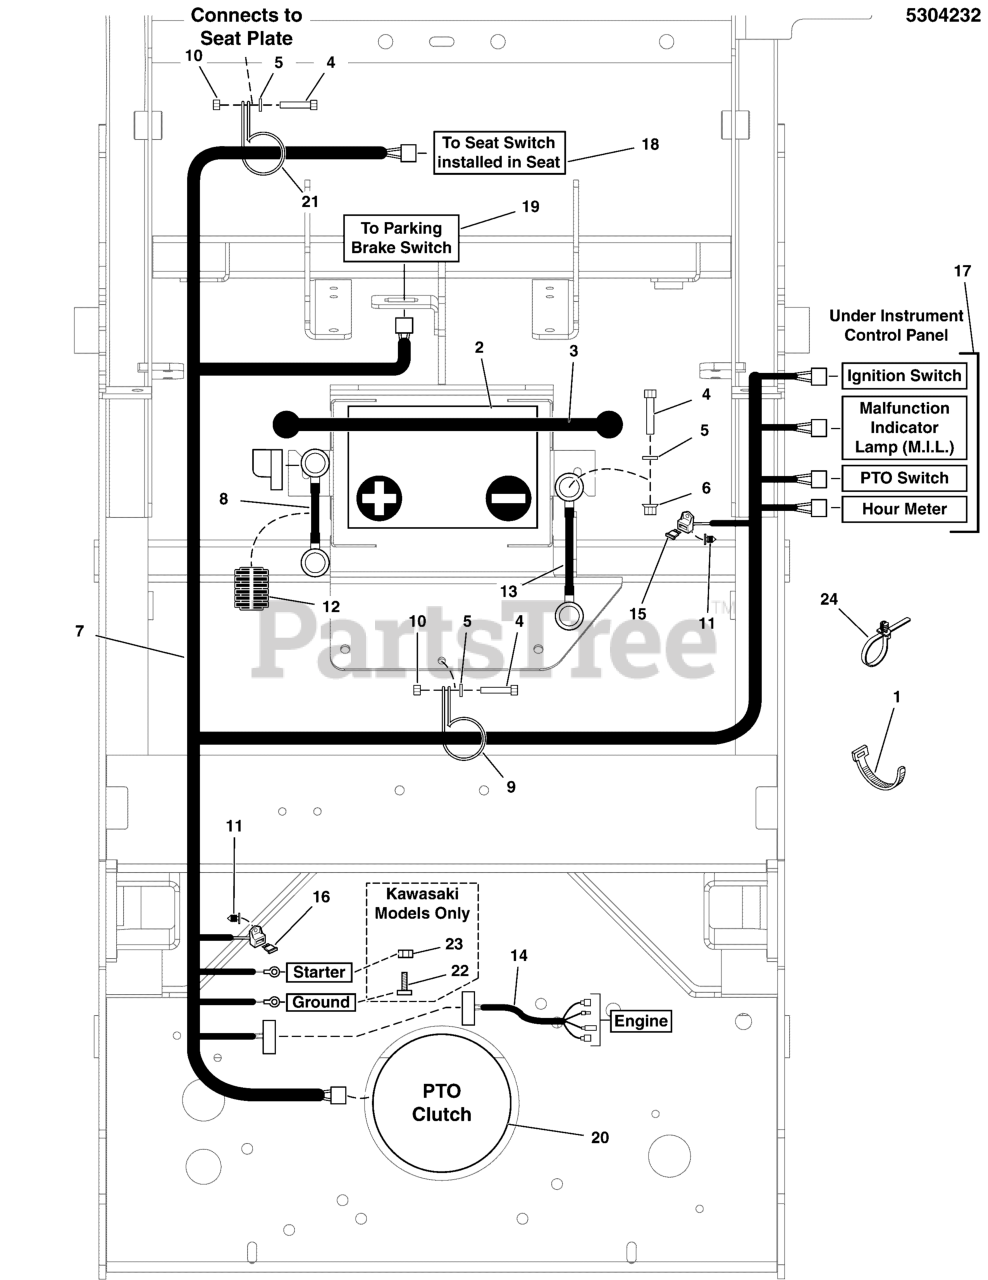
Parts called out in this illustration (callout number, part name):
1	TIE, SELF-LOCKING, 12"
3	STRAP, BATTERY, 14 LONG, Rubber
4	BOLT, 1/4"-20 X 3/4" GD5 YZ
5	WASHER, 1/4 SAE
6	NUT, 1/4-20 HEX SERR. FLANGE
7	WIRE HARNESS, MAIN, LG, ZTR
7	HARNESS, Wiring, Large ZTR
8	BATTERY CABLE, POS, 35, 1/4-5/16
9	CLAMP, VINYL INSULATED, 1.00
10	NUT, 1/4-20 Hex Nylock Flange
11	FIR TREE MOUNT, PACKARD
12	WIRE LOOM, 3/8 ID X 30 IN
13	CABLE, BATTERY, NEG, 30, 1/4-5/16
14	WIRE HARNESS, JUMPER, KAWI - LARGE HARNE
15	FUSE, ATO, 25 AMP
16	FUSE, ATO-15 (15 AMP)(SV)
17	Refer to: Instrument Control Panel Group
18	Refer to: Seat Mount & Floor Group
19	SWITCH, DP NO/NC SNAP-IN
20	Refer to: Engine & PTO Group
21	CLAMP, VINYL INSULATED, .625
22	BOLT, M8-1.25 X 20 MM GD 8.8
23	NUT, HEX, M8-1.25, CZ, GD 8.8
24	TIE, SELF-LOCKING, 8", PUSH MOUNT
